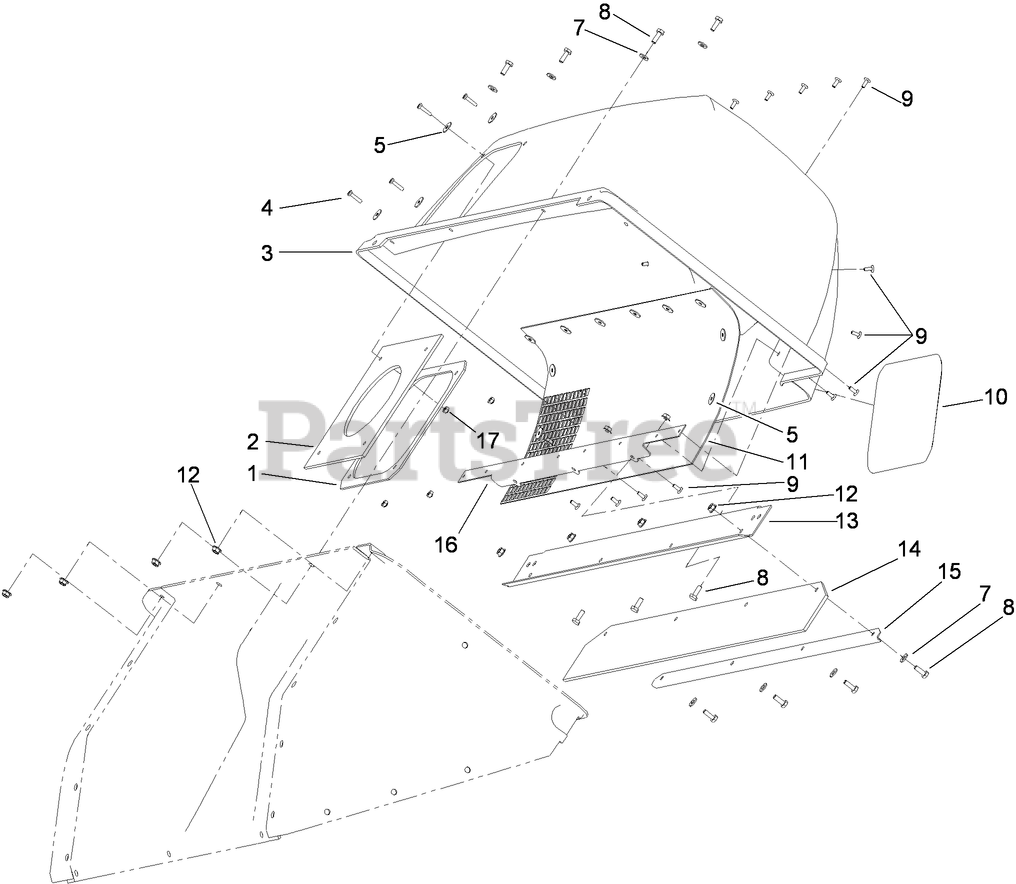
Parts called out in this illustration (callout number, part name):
1	CLAMP-SEAL
2	SEAL-CHUTE
3	DFS HOOD ASM
4	SCREW-PPH
5	WASHER-FLAT
7	WASHER-FLAT
8	SCREW-HH
9	RIVET-BLIND
10	DECAL
11	SCREEN-BAGGER
12	NUT-HF
13	PLATE-REAR
14	SEAL-DOOR
15	STRAP-HOLD DOWN
16	SUPPORT-SCREEN
17	NUT-LOCK, NI
